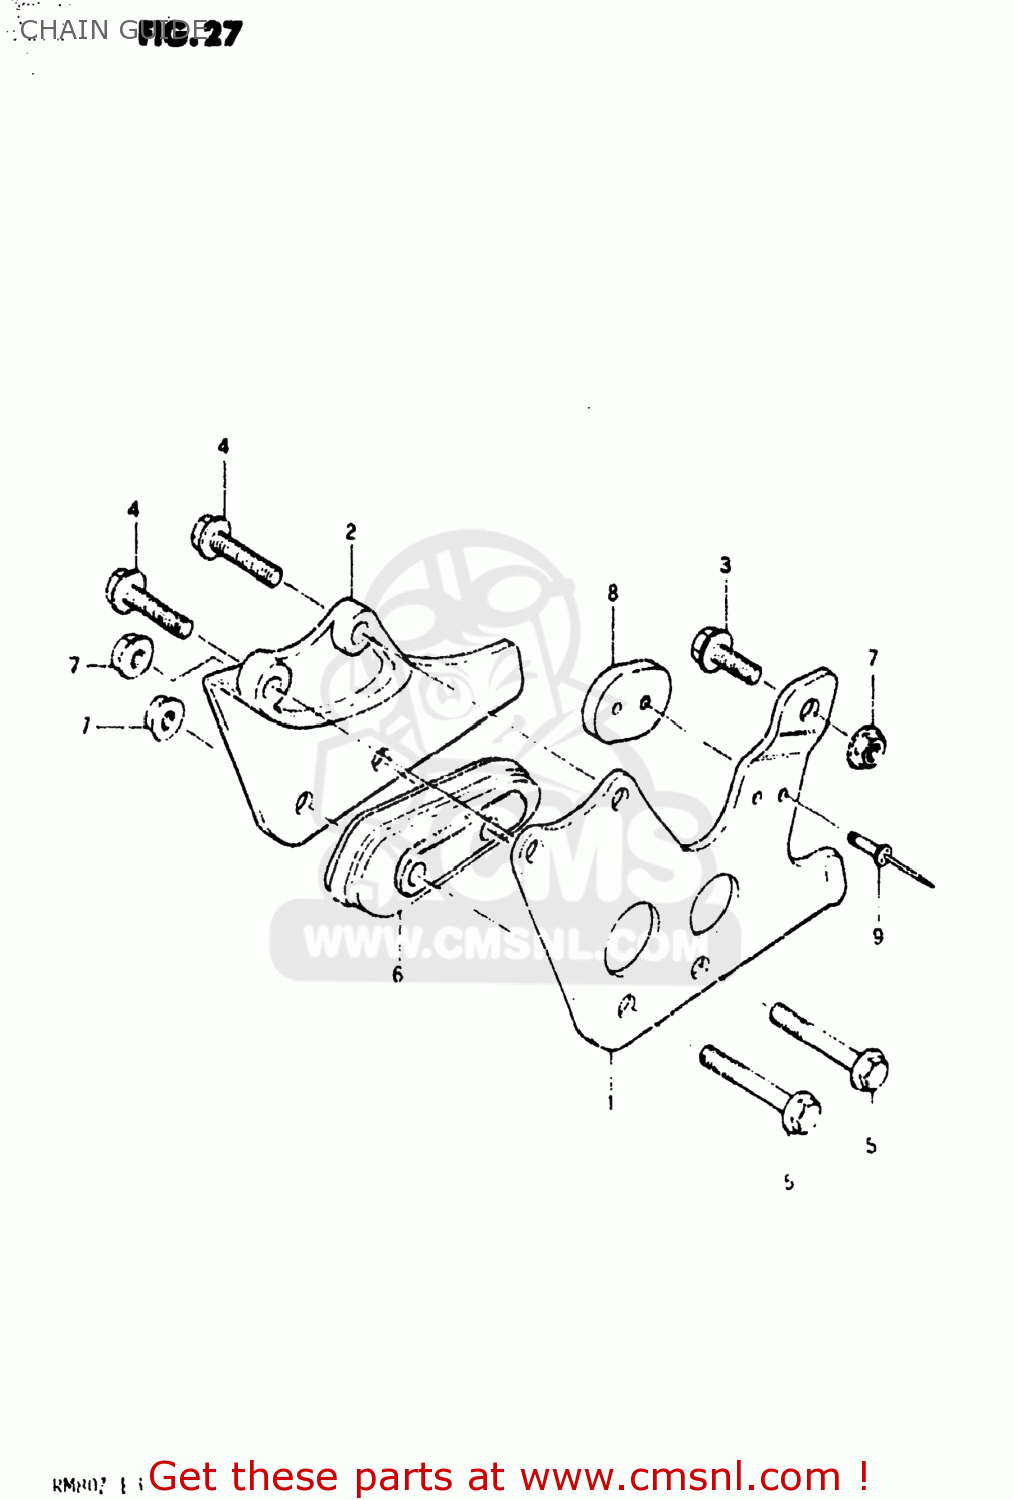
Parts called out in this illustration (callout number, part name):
1	GUIDE,CHAIN
2	PLATE,CHAIN GUIDE INNER
3	BOLT
4	BOLT
5	BOLT
6	DEFENSE,CHAIN GUIDE
7	NUT
8	PAD,DRIVE CHAIN GUIDE
9	RIVET
